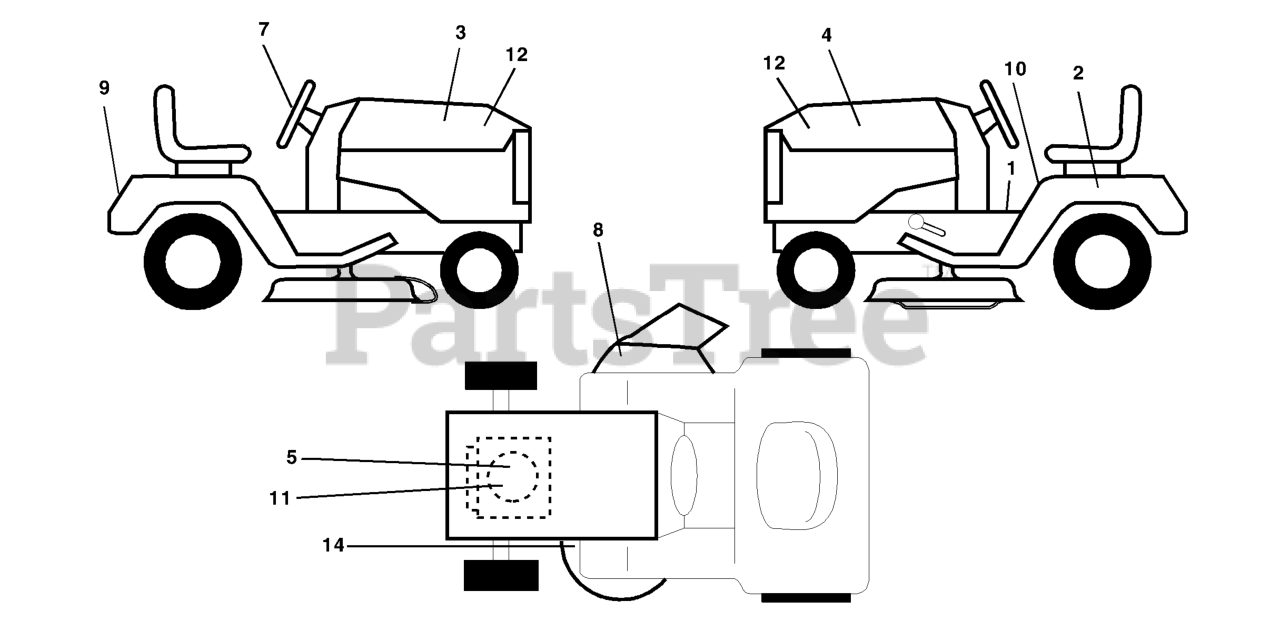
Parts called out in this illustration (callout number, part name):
2	DECAL BTRY SYMBOLS
5	DECAL HP ENGINE
7	DECAL.WHEEL.STEERING.HUSQ.PERM
8	DECAL.WARN.KEEP.HAND.AWAY
9	DECAL, FENDER
10	DECAL FENDER DANGER
11	DECAL, ENGINE LOGO
12	DECAL, HOOD SIDE
14	DECAL V BELT SCHEMATIC
